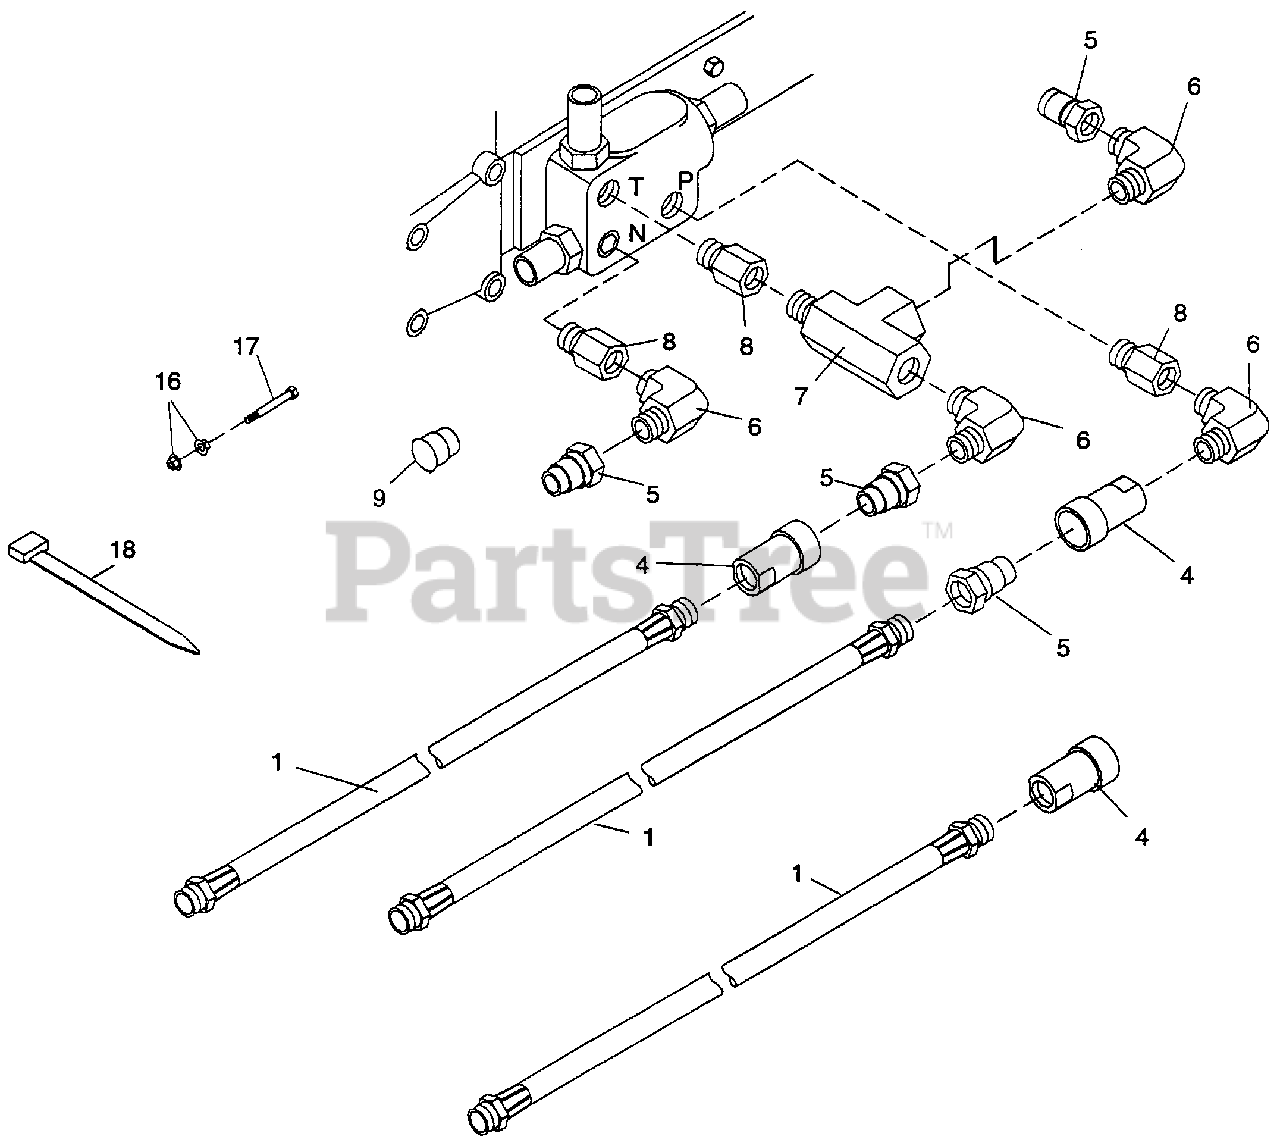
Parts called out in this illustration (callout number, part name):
1	Hose, 3/8 112 3/4 SAE M 3/8 NPT M
4	Quick coupler, 3/8 NPT female
5	Quick coupling, 3/8 NPT male
6	Elbow, Male 3/8 NPT x 90°
7	Run tee, 3/8 NPT
8	Adapter, 3/8 BSTP Male 3/8 NPT
9	Dust plug - blue
16	1/4 NC Flanged locknut
17	1/4 NC x 4 Hex head cap screw GR5
18	Hydraulic hose tie, 7" long
